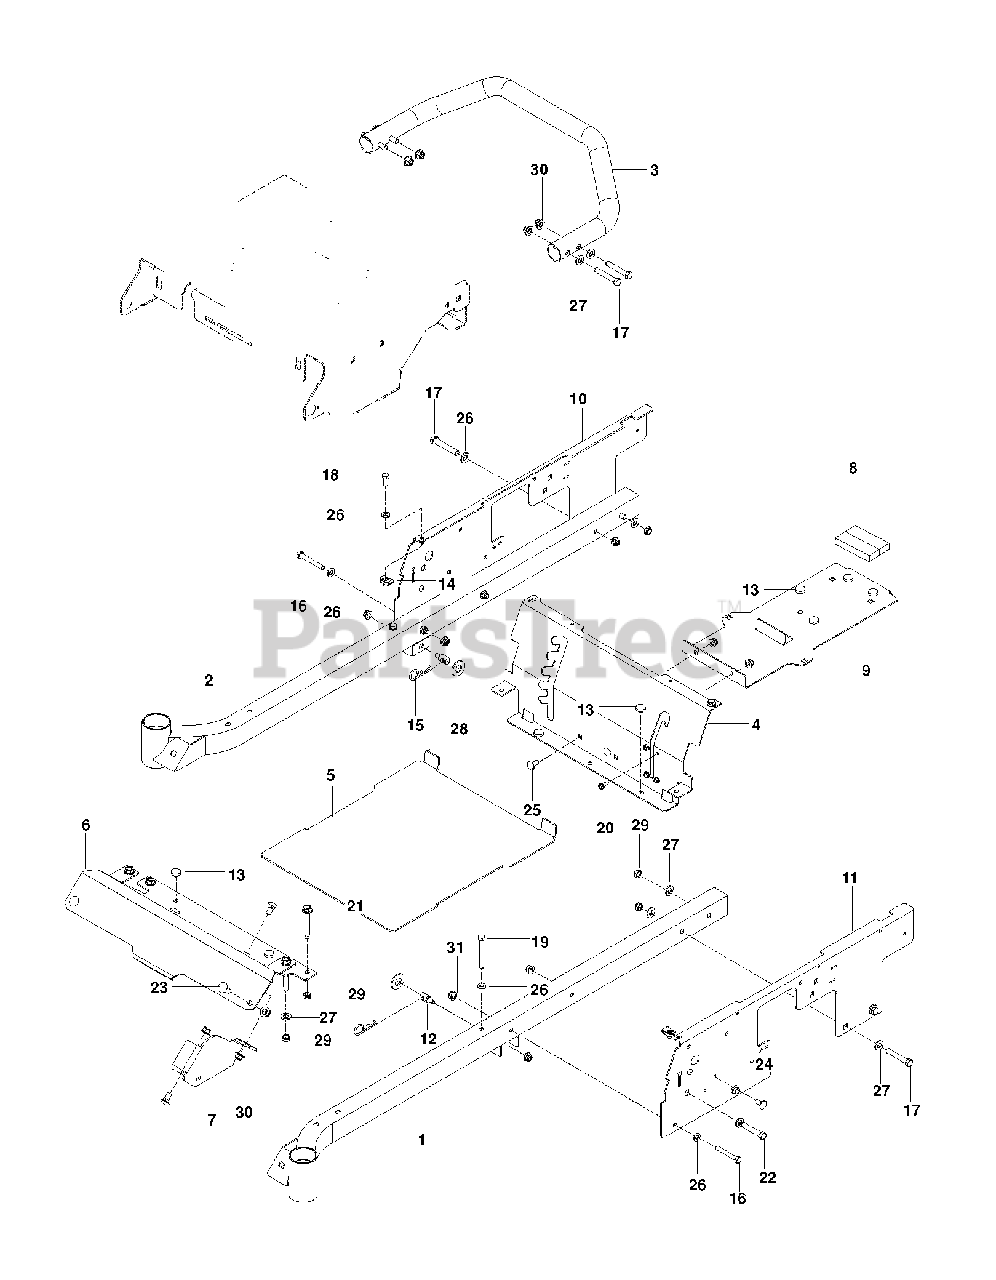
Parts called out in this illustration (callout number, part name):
1	FRAME TUBE, LH, ORG
2	FRAME TUBE, RH, ORG
3	IMPACT BAR, ORG
4	PANEL.SEAT.SUPPORT.ORANGE
5	PAN, FLOOR W/DECALS, HUS
6	FOOT REST, ORG
7	BRACKET, FRONT DECK, BLK
8	FOAM STRIP, FUEL TANK
9	SUPPORT, TANK/BATT, BLK
10	PLATE.RH.SIDE.ORANGE
11	PLATE.LH.SIDE.ORANGE
12	STUD.FASTNER.W/ANTI-ROTATE
13	GROMMET, BUMPER
14	U-CLIP 5/16-18 NUT RETAINER
15	HAIRPIN #4
17	HCS 3/8C X 2 1/4
18	HCS 5/16C X 3/4
19	HCS 5/16C X 2-3/4
20	SCREW 1/4 X 5/8
21	ENGINE BOLT, SPECIAL
22	HCS 1/2C X 2 3/4
23	RHSNB 3/8C X 1
24	RHSNB 3/8-16 X 3/4 GR5 ZD
25	BOLT 5/16C X 3/4" CARRIAGE
26	FLAT WASHER 5/16 SAE
27	WASHER 3/8 SAE FLAT
28	WASHER 5/8 FLAT
29	NUT HEX 3/8-16 NYLON, THIN
30	NUT 3/8-16 HEX FLG NYLOC ZD
31	5/16-18 NYLOC FLANGE NUT
